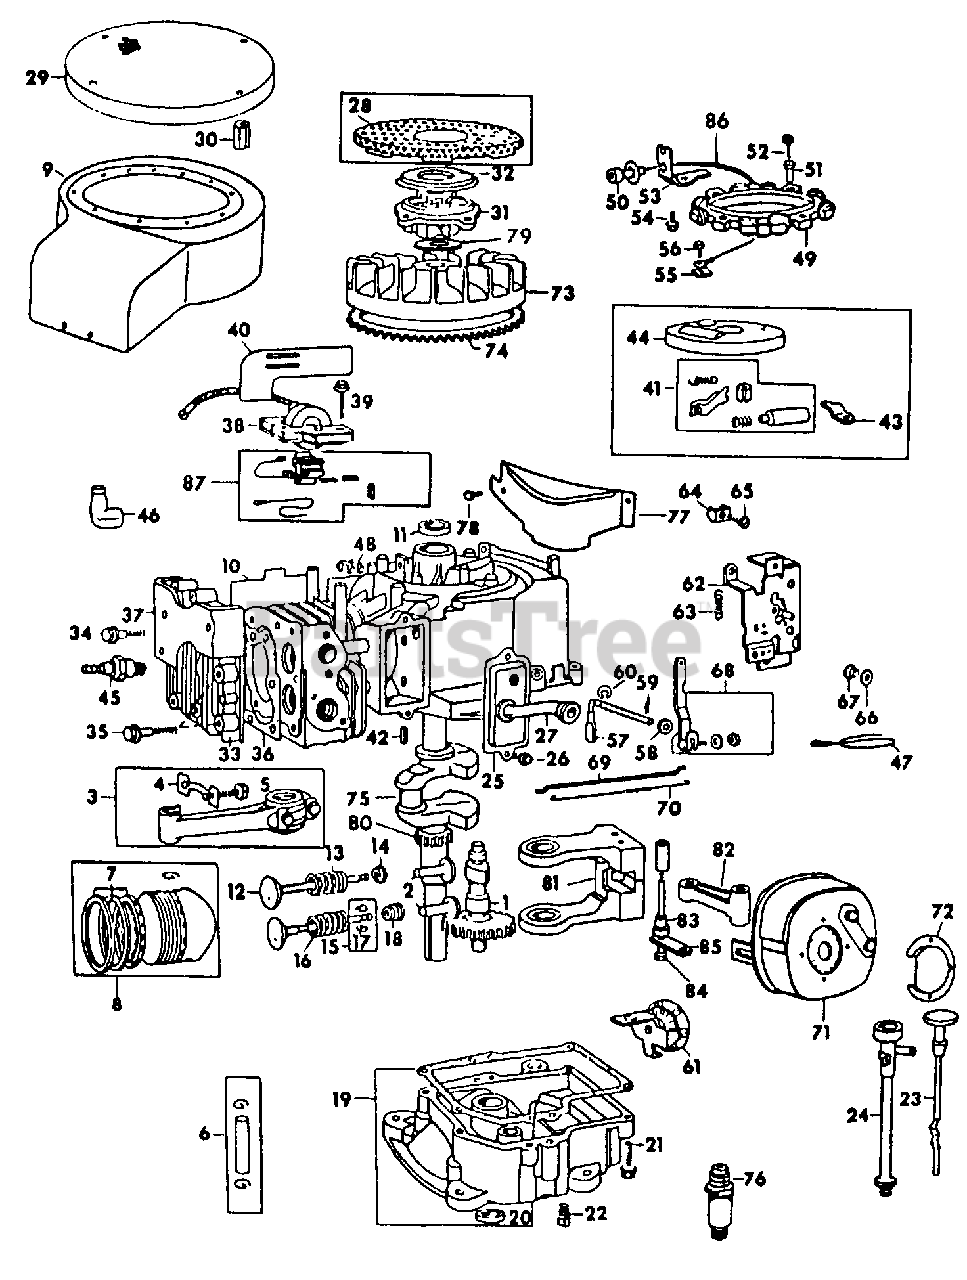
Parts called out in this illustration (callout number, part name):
2	Tappet, Valve
3	Rod Assy, Connecting
4	Lock, Screw Head
5	Screw, Connecting Rod
6	Pin, Piston
7	Ring Set, Piston Chrome
8	Piston Assy, Std
9	Housing, Blower
10	Shield, Cylinder
12	Valve, Intake
13	Spring, Intake Valve
14	Retainer, Intake Valve
15	Valve w/Keepers, Exhaust
16	Spring, Exhaust Valve
17	Retainer, Roto-Coil
18	Roto-Coil, Exhaust Valve
20	Seal, Oil
21	Screw, Crankcase Cover Mtg
22	Plug, 3/8-18 Auto Sq Hd Oil Drain
23	Not used in this application
24	Not used in this application
25	Breather, Valve Chamber
26	Screw, Breather Mtg
27	Tube, Breather
28	Screen, Rewind Starter
29	Screen, Blower Housing
30	Spacer, Blower Housing Screw
31	Housing, Rewind Starter
32	Cover, Housing
33	Head, Cylinder
34	Screw, Cylinder Head, Short
35	Screw, Cylinder Head, Long
36	Gasket, Cylinder Head
37	Cover, Cylinder Head
38	Armature Assy, Magneto
39	Screw, Armature Mtg
40	Guide, Air
41	Kit, Breaker Point & Condenser
42	Key, Flywheel
43	Clamp, Condenser
44	Cover, Breaker Point
45	Plug, Resistor Spark
46	Elbow, Spark Plug Insulator
47	Wire Assy, Ground
49	Stator w/Bracket, Alternator
50	Rectifier
51	Bushing, Stator
52	Screw, Stator Mtg
53	Bracket, Fuse
54	Screw, Bracket Mtg
56	Screw, 8-32 X 3/8 Hex Hd
57	Crank, Governor
58	Washer, Governor Crank
59	Cotter, Governor Crank
60	Retainer, Governor Crank
61	Gear, Governor
62	Plate, Governor
63	Spring, Governor
64	Clamp, Casing
65	Screw, Hex Hd w/Lockwasher
66	Washer, Insulating
67	Collar, Insulating
68	Lever Assy, Governor
69	Link, Governor
70	Spring, Governor Link
71	Muffler
72	Deflector
73	Flywheel w/Ring Gear
74	Gear, Flywheel Ring
76	Plug, Oil Minder
77	Guard, Ring Gear
78	Screw, Guard Mtg
79	Washer, Spring
80	Gear, Timing
81	Counterweight
82	Link, Counterweight
83	Spacer, Counterweight
84	Bolt, Counterweight
85	Shim, Screw Head Lock
86	Cable Assy, Diode & Connector
87	Module, Ignition
